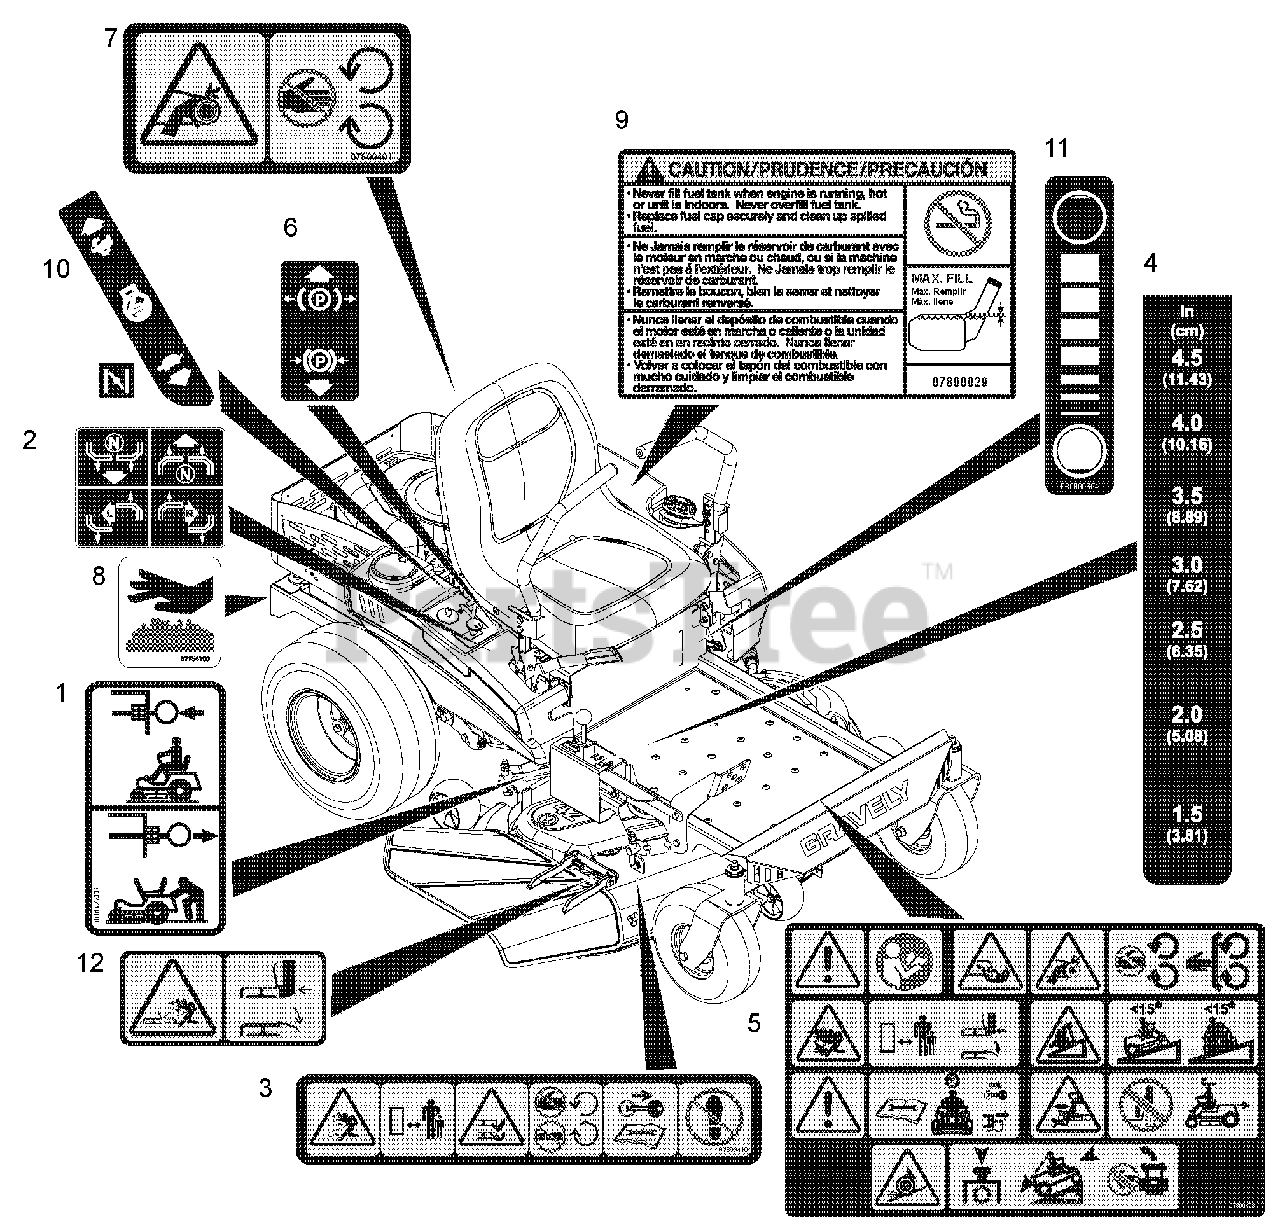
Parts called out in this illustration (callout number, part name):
1	Decal, Transmission Disconnect
2	Decal, Instructional Steering
3	Decal, Safety – Mower Deck
4	Decal, Cut Height
5	Decal, Safety – Main
6	Decal, Parking Brake Lever
7	Decal, Safety – Guarding
8	Decal, Hot Surface
9	Decal, Fuel Warning
10	Decal, ZT XL Control
11	Decal, Fuel Level
12	Decal, Safety – Deck Guarding
